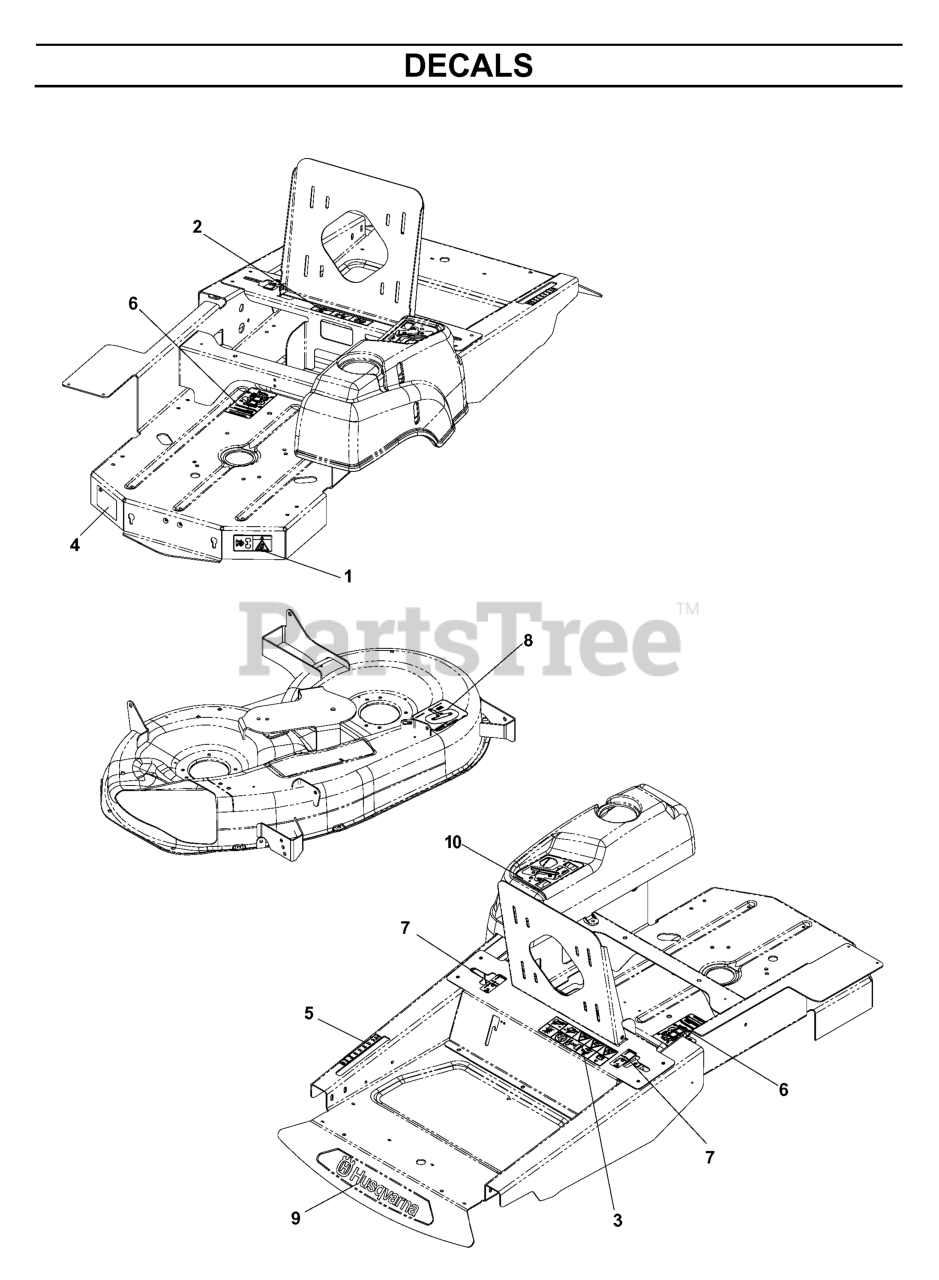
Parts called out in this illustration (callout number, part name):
1	DECAL, BELT DRIVE
2	EURO DECAL-BATTERY WARNIN6
3	DECAL, WARNING
4	DECAL, DO NOT TOW
5	DECAL, HEIGHT, CE
6	DECAL, SERVICE
7	DECAL, MOTION CONTROL
8	DECAL, BELT
9	DECAL, HUSQ 12" BLUE
10	DECAL, IGNITION CONSOLE
